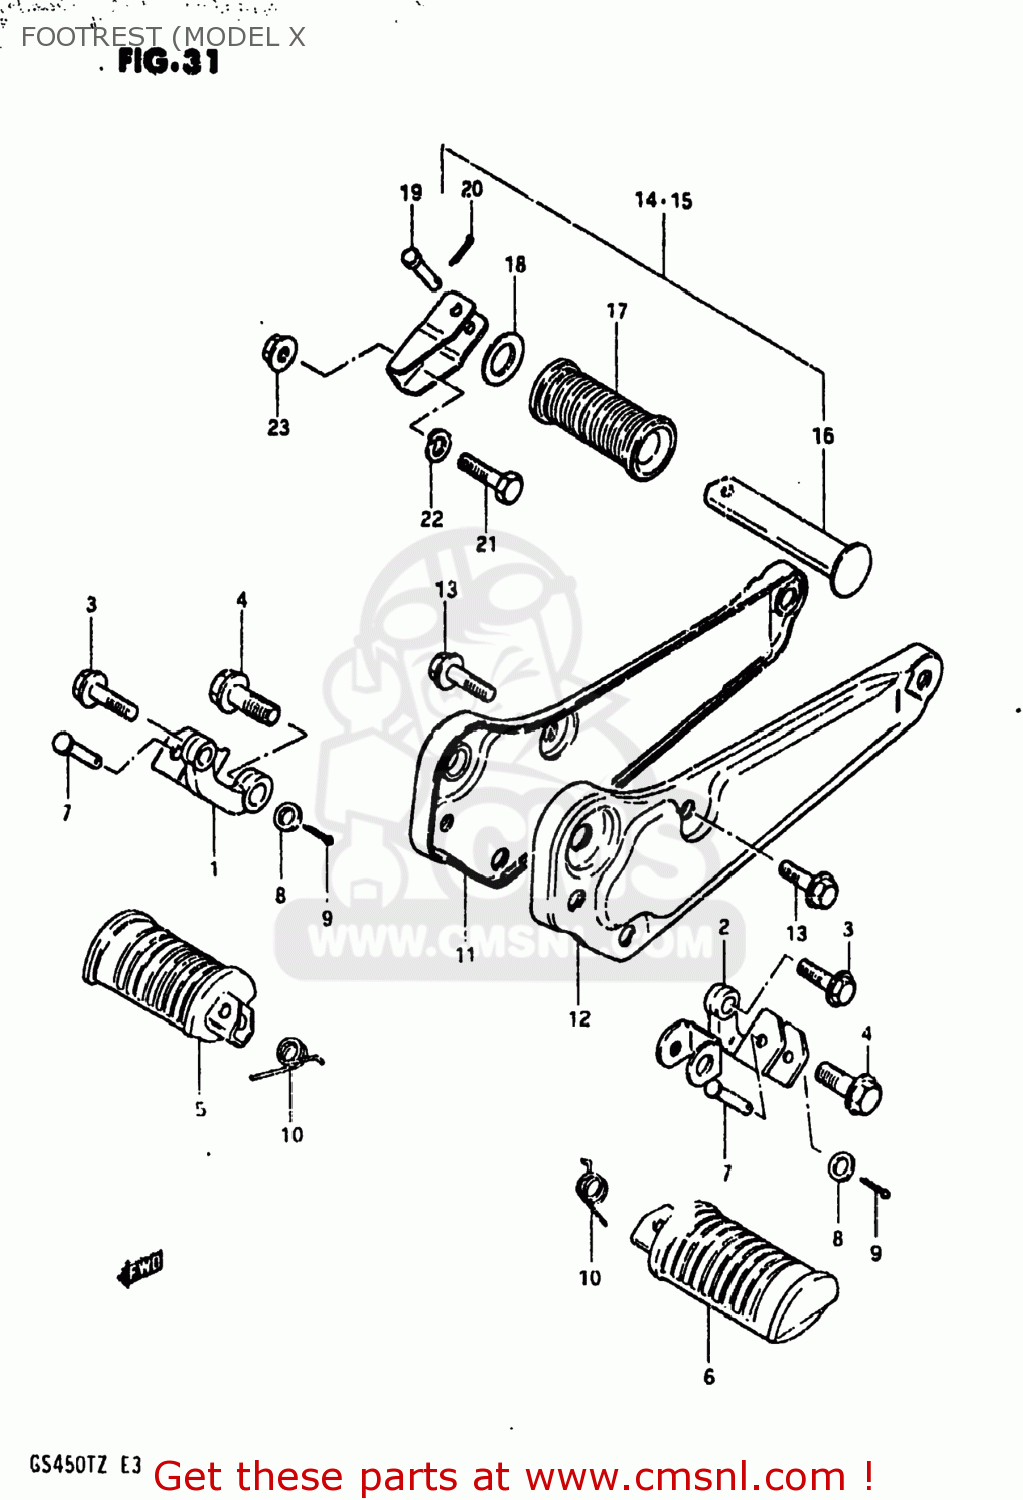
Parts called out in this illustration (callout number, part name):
1	BAR,FRONT FOOTREST,RIGHT
2	BAR,FRONT FOOTREST,LEFT
3	BOLT
4	BOLT
5	RUBBER,FRONT FOOTREST
6	FOOTREST
7	PIN
8	WASHER
9	PIN
10	SPRING
11	BRACKET
12	BRACKET
13	BOLT
14	FOOTREST ASSEMBLY,REAR
15	FOOTREST ASSEMBLY,PILLION
16	BAR,PILLION FOOTREST
17	RUBBER,PILLION FOOTREST
18	WASHER (19.5X32X2)
19	PIN
20	PIN
21	BOLT,M10X1.25X
22	LOCK WASHER
23	NUT
